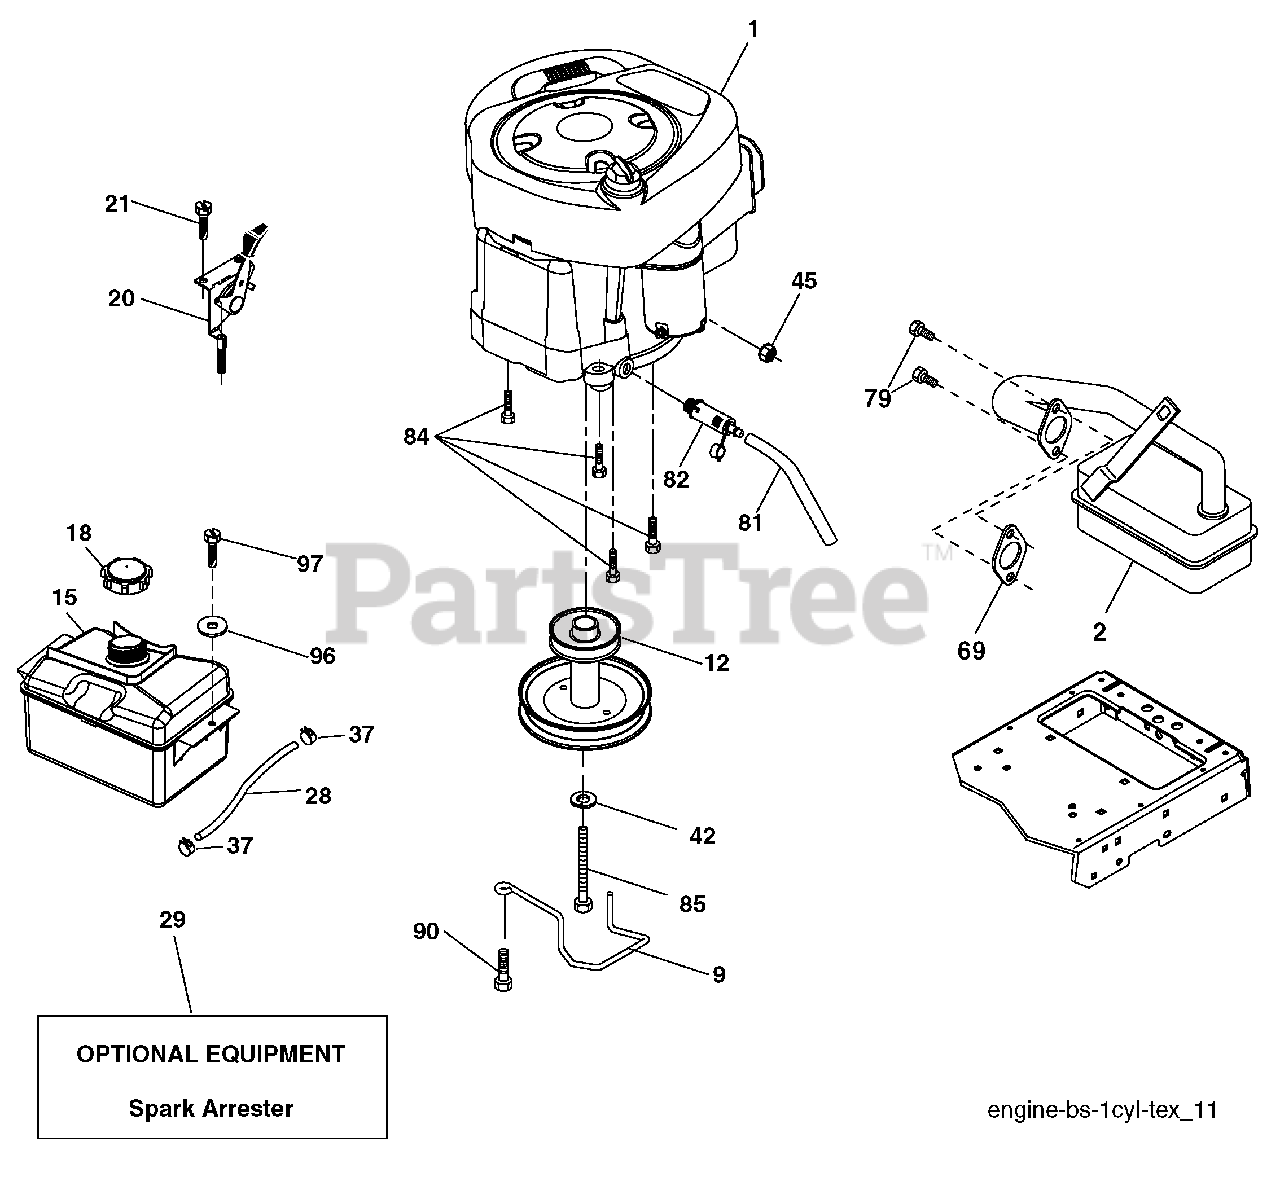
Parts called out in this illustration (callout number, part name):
2	Muffler
9	Keeper Belt Engine
12	Pulley Engine
15	Tank Fuel 1.5
18	Cap
20	Control Throttle
21	Screw #10 x 0.750
28	Fuel Line
29	Spark Arrester Kit
42	Washer Lock 7/16
45	Nut Keps Hex 1/4-20 unc
69	Gasket
72	Screw 5/16 - 18 x .75
81	Tube Drain Oil Easy
82	Valve Oil Drain
84	Screw 3/8-16 x 1-1/4
85	Bolt Hex 7/16-20 x 4 Gr. 5
90	Screw 3/8-16 x 1
96	Washer 9/32 x 7/8 x 16 Ga.
97	Screw 1/4-20 x 3/4
